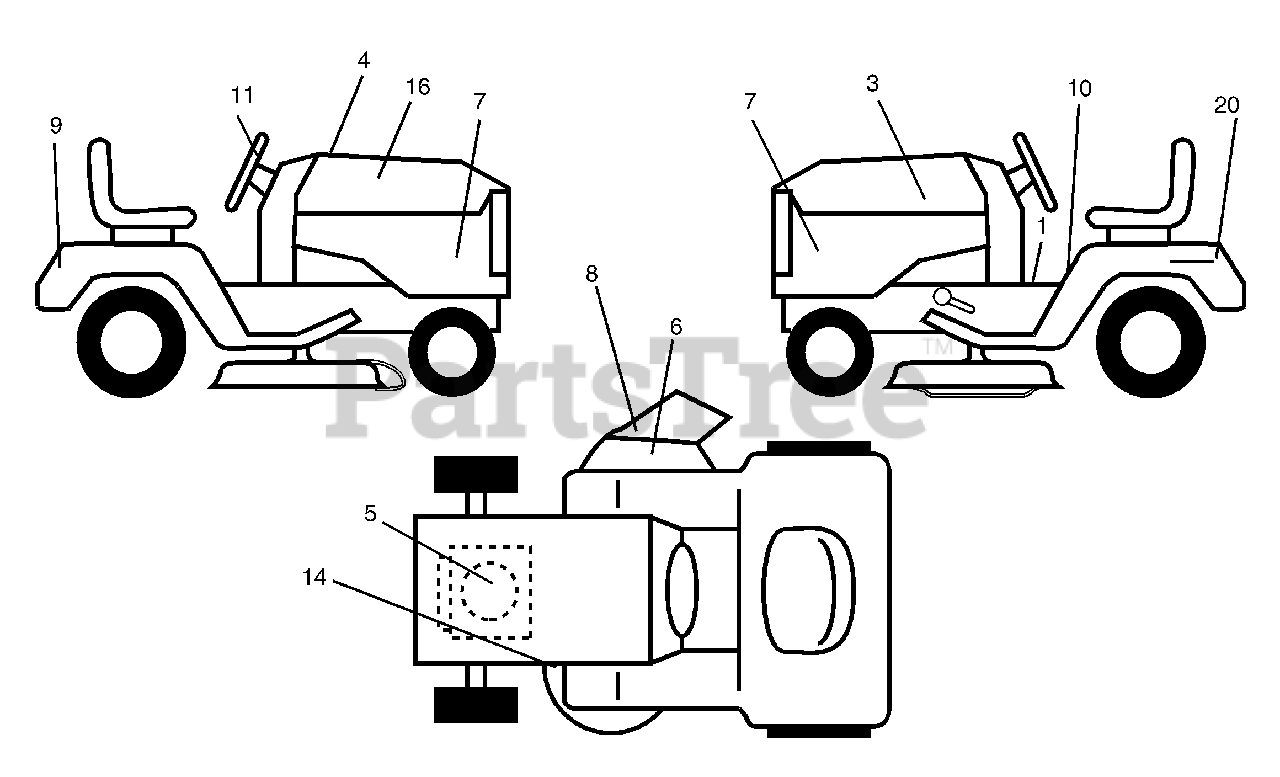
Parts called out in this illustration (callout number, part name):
3	Decal Hood LH
4	Decal Replace
5	Decal HP Engine
6	Decal Deck "B" 42"
7	Decal Side Panel
8	Decal Warning Mult-Language
9	Decal Fender Logo
10	Decal Fender Danger E/F
11	Decal Ins Strg Whl
14	Decal V-Belt Schematic
16	Decal Hood Rh
20	Decal Bat Dan/Psn
